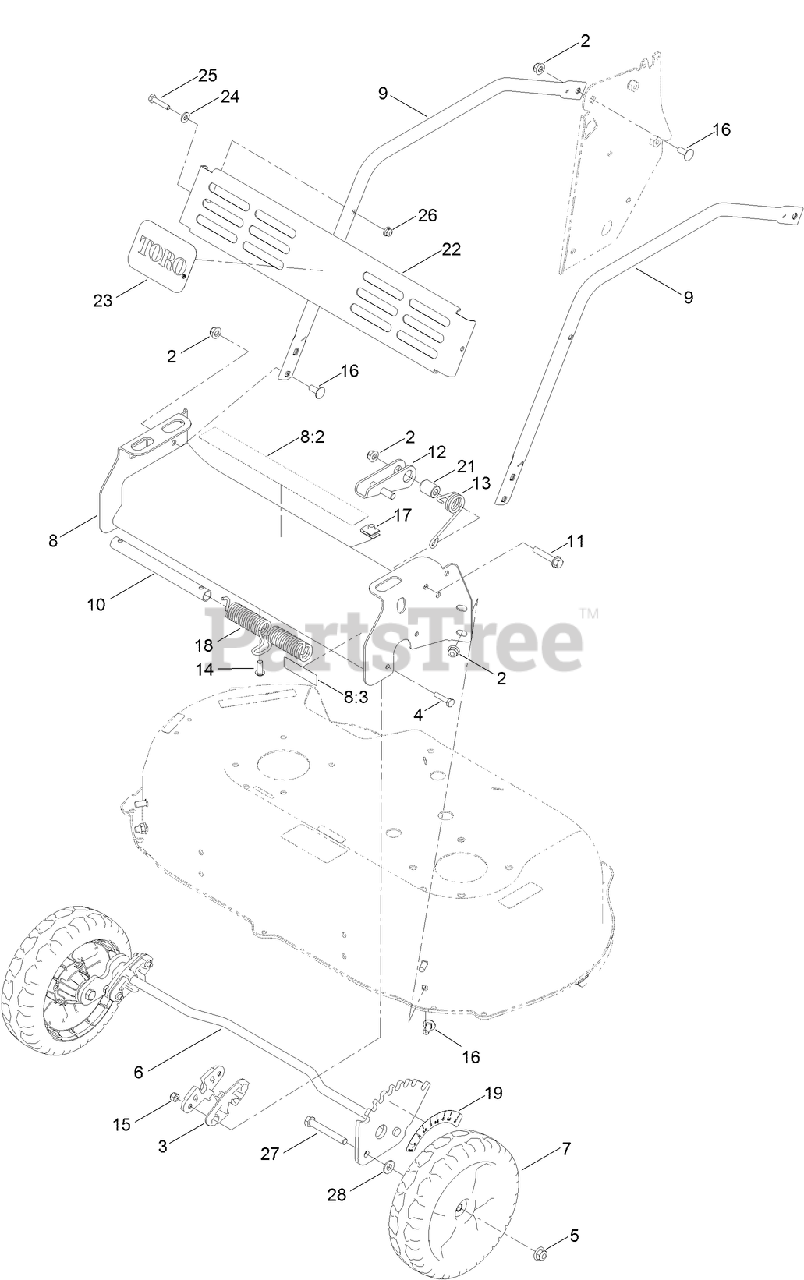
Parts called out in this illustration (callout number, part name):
2	NUT-HF, NI
3	BUSHING-FRONT
4	SCREW-HH
5	NUT-HF, NI
6	AXLE-FRONT
7	WHEEL
8	FRONT BUMPER ASM
8:3	DECAL-WARNING
10	MANDRELL-SPRING
11	SCREW-HWH
12	LOCK-HEIGHT, ADJUSTMENT
13	SPRING-TORSION
14	SCREW-HSBH
15	NUT-LOCK, NI
16	SCREW-CARR
17	NUT-U
18	SPRING-TORSION
19	DECAL-HOC, FRONT
21	SPACER
24	WASHER-FLAT
25	SCREW-HH
26	NUT-HF
27	SCREW-HH
28	SPACER-COVER, WHEEL
